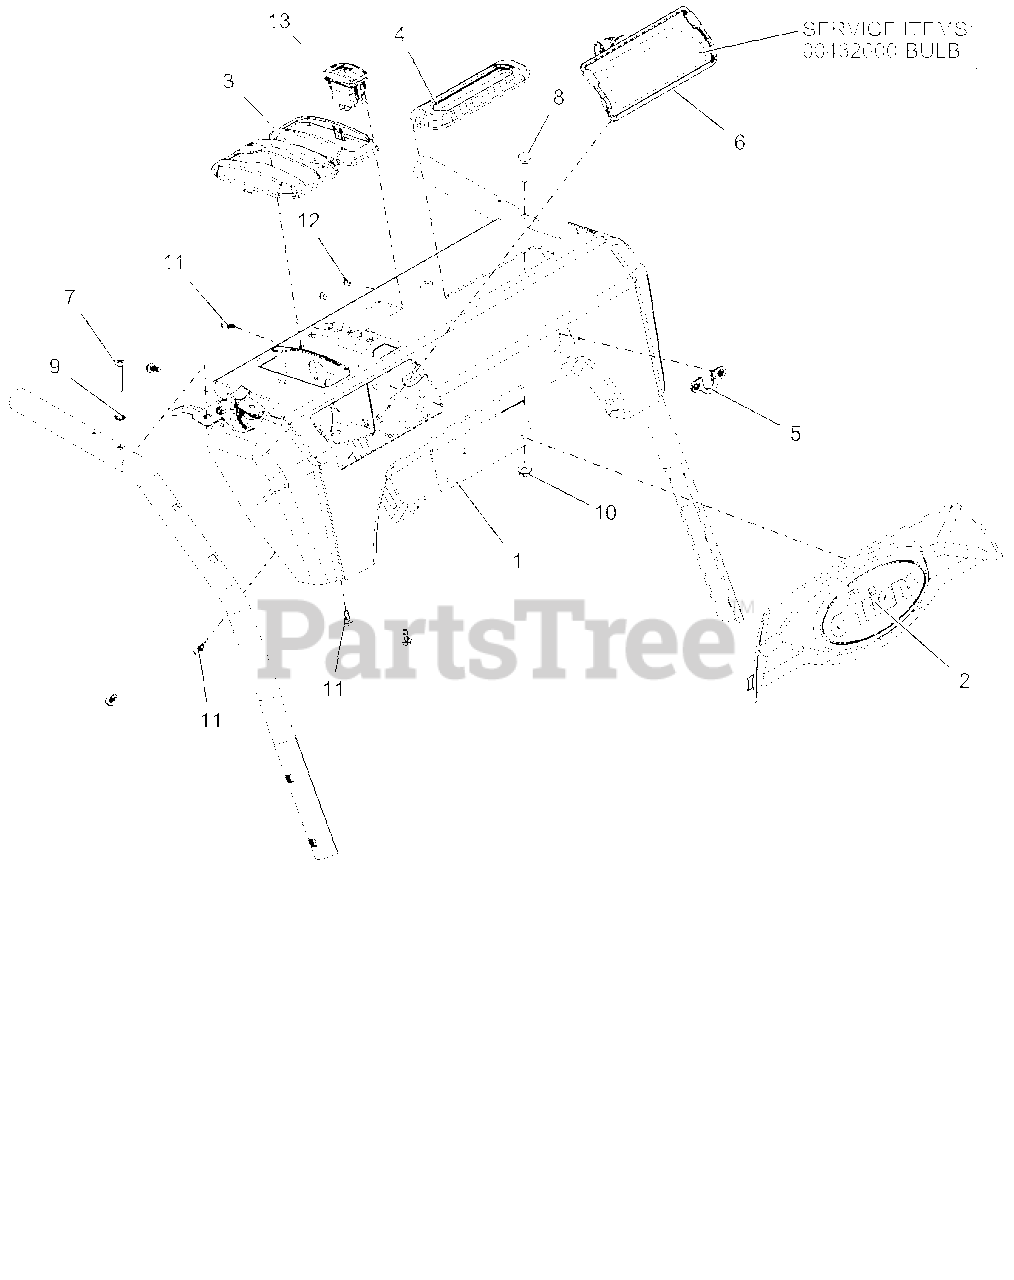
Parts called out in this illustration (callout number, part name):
1	CONTROL PANEL W/DECAL HYDRO-TK
2	BEZEL, DASH-ARIENS LG DASH
3	BEZEL, SHIFT - HYDRO SNOW
4	GROMMET, BOOT, QUICK TURN
5	GROMMET, CABLE, QUICK TURN 2
6	BULB, LIGHT-HALOGEN 20W
6	HEADLIGHT ASY, HALO 20W 2SHOT
7	SCR-MCH .25-20X1.50 OVAL HD
8	BLT-RDHDXLSQNK.25-20X1.25 G5ZC
9	WSHR-LK-INT .250 TH TYA
10	@NUT-LK-CTR-FLG .25-20 YWZC
11	SCR-TAP #10X.50 BOSS INDHXHD
12	RVT-POP #43 .125X.313 STL ZINC
13	SWITCH,ROCKER SPST-ON/OFF
